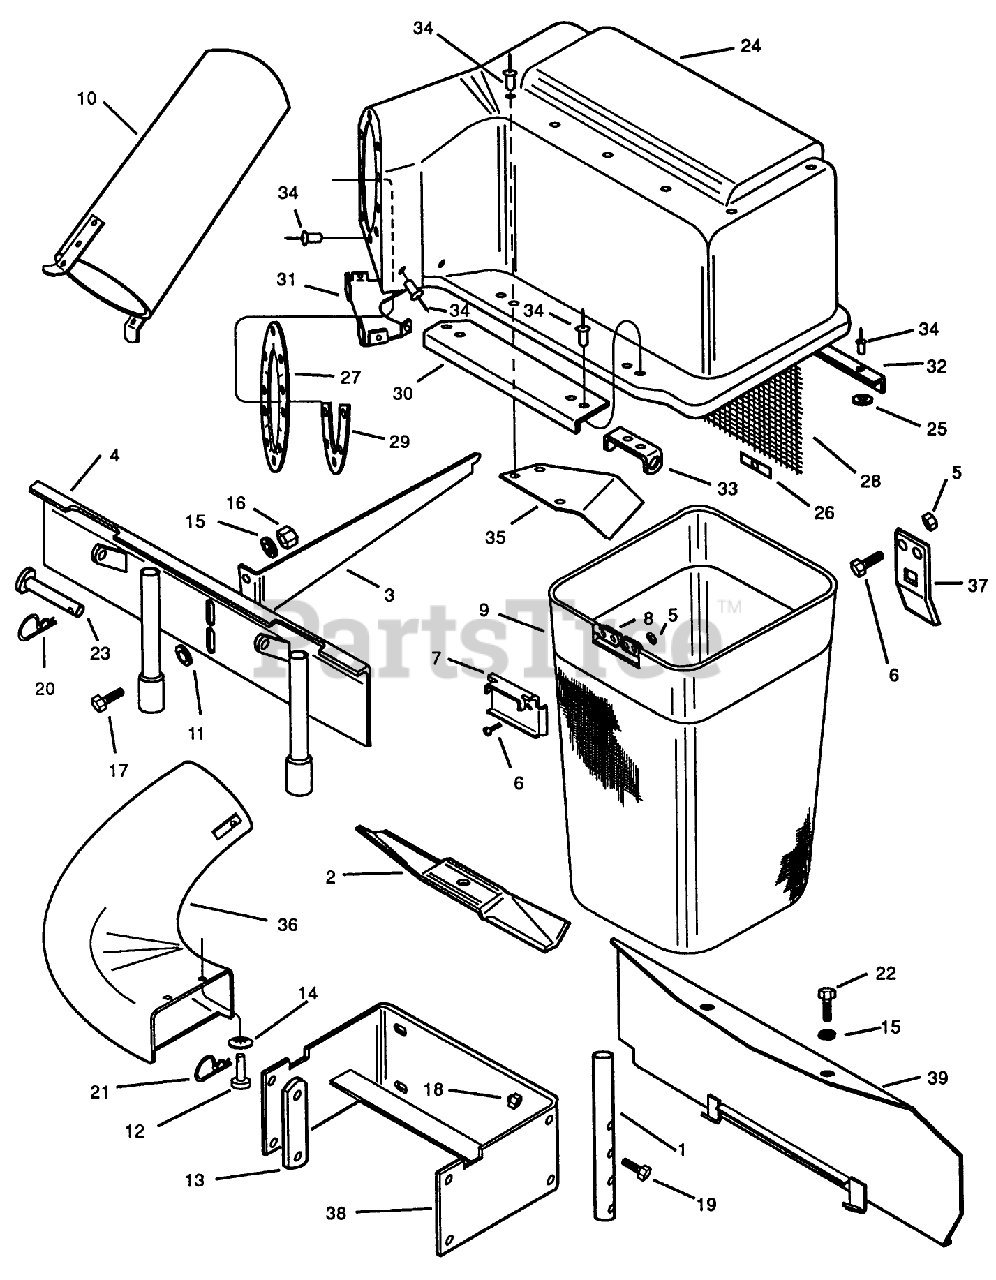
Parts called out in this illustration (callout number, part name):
1	BAR MOUNTING
2	BLADE
3	BAR - COVER LATCH
4	FRAME ASSY *B
5	NUT-LOCK, CONE
6	SCREW
9	GRASS BAS ASSEMBLY
10	TUBE ASSY
12	PIN-CLEVIS
16	NUT SS
18	NUT-LOCKING
20	PIN-HAIR
21	PIN - SPRING CLIP
22	SCREW - HEX
24	COVER & DECAL ASSY
32	ANGLE - COVER *B
36	CHUTE & DECAL AY
